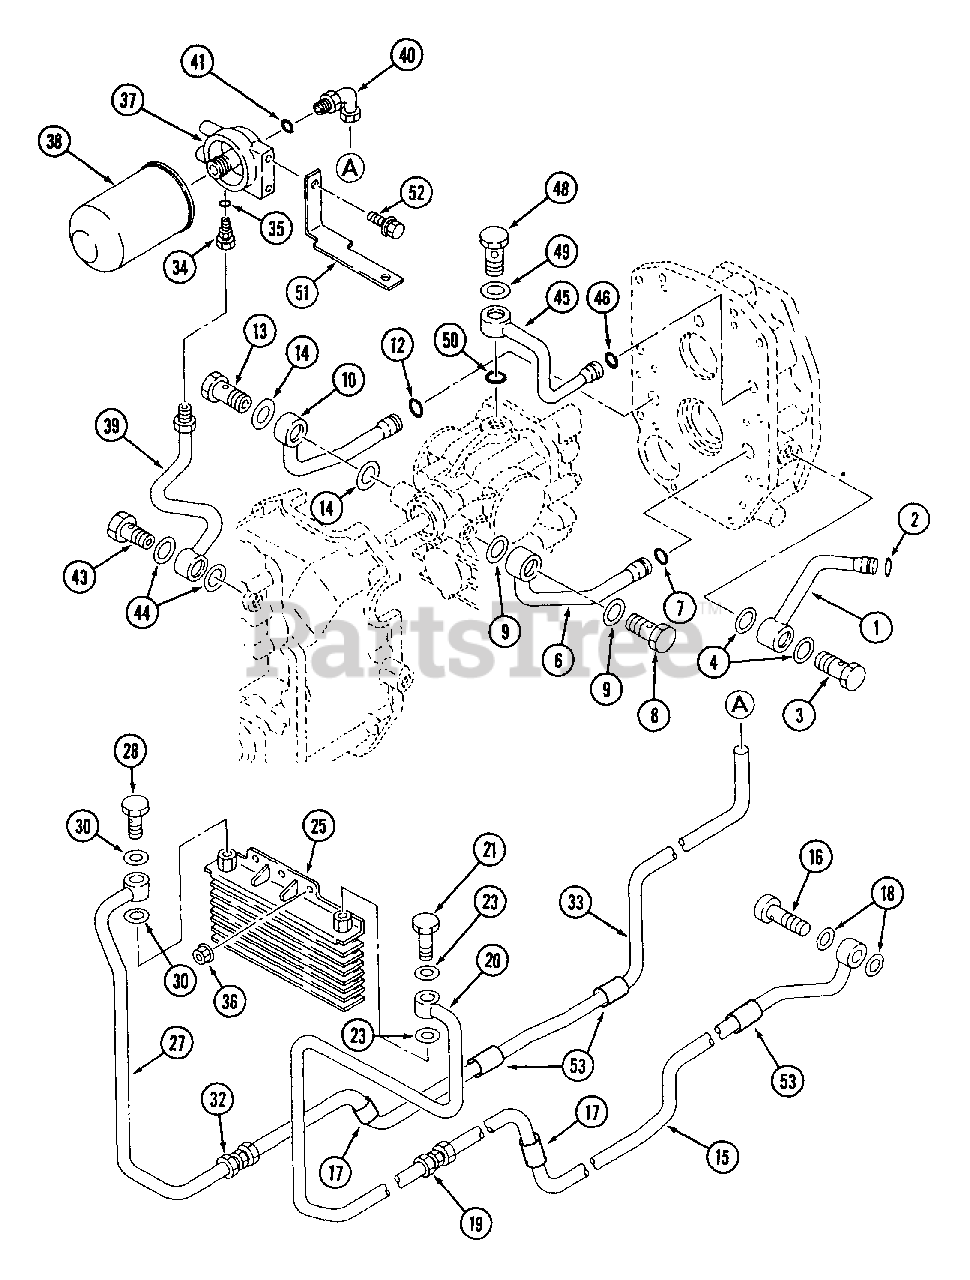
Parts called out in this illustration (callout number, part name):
15	Pipe, P Ass'y.
17	Pipe
18	Seal, Washer
20	Pipe Q Ass'y.
27	Pipe S Ass'y.
33	Pipe, U Ass'y.
34	Body (Nipple)
39	Pipe 1 Ass'y.
44	Seal, Washer
49	Seal, Washer
